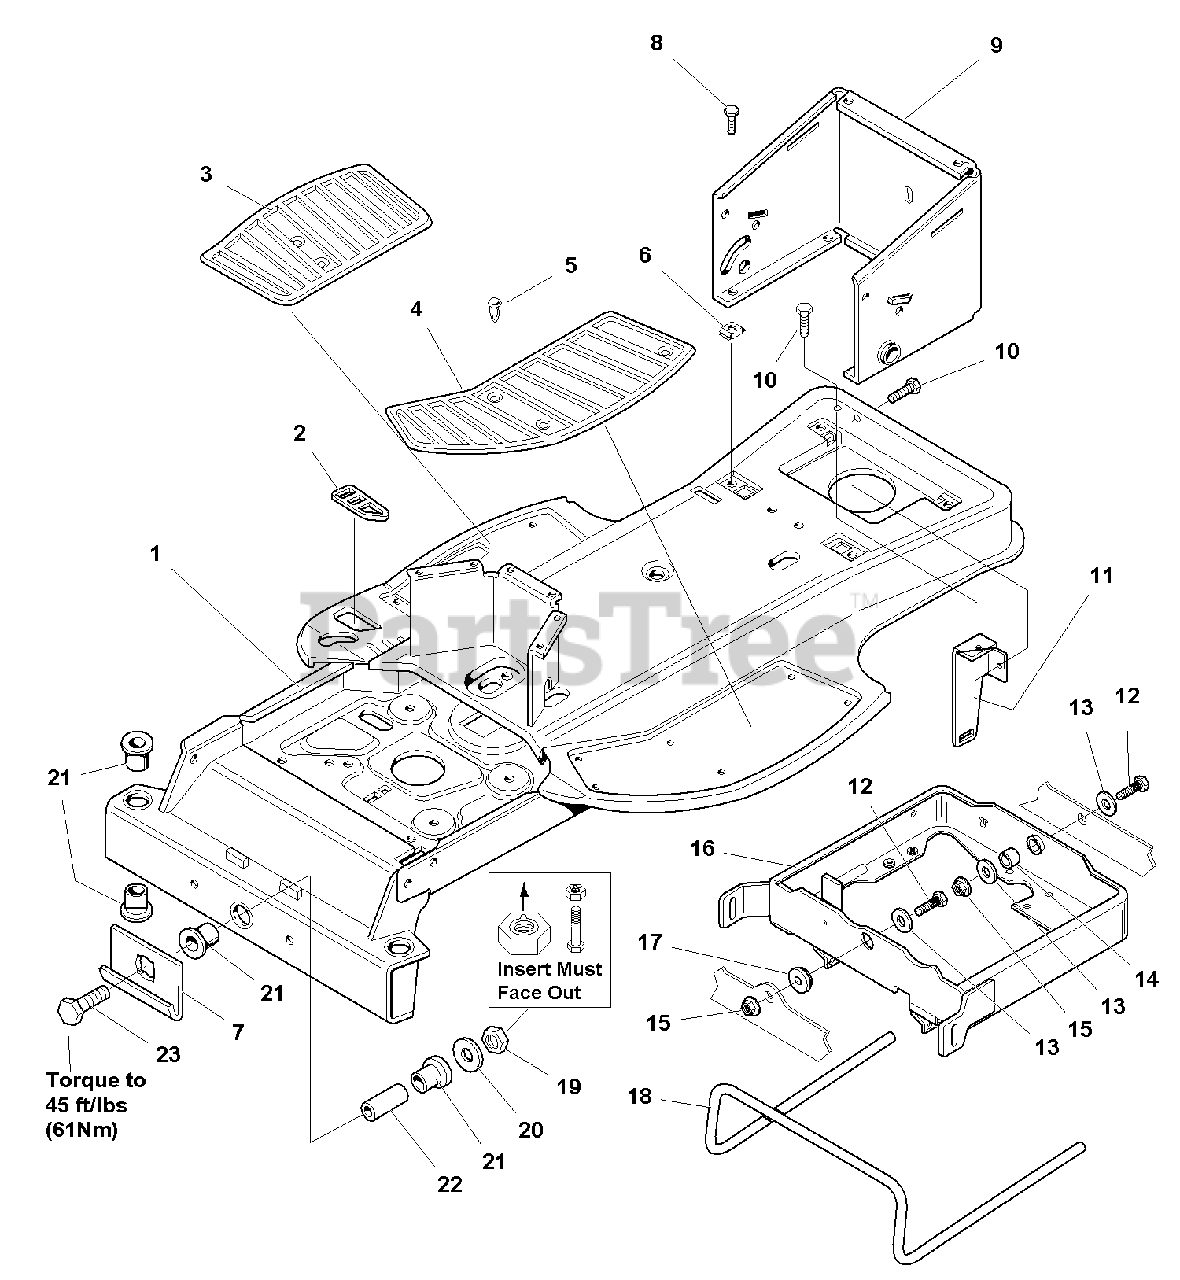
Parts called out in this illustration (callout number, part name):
1	FRAME ASSEMBLY
3	PAD, Footrest RH
4	PAD, Footrest LH
5	FASTENER, Panel
6	NUT, Speed 5/16-18
7	"J" HOOK, Hitch
8	SCREW, Hex Head Flange Lock, 5/16-18 x 3/4
9	WRAPPER ASSEMBLY, Hydro
10	CAPSCREW, Hex Head Flange Whiz Lock, 5/16-18 x 3/4
12	CAPSCREW, Hex Head, 1/2-13 x 1/2
13	WASHER
15	NUT, Hex Head, 1/2-13
16	CARRIER ASSEMBLY, Hydro
18	BAR, Torsion, Hydro
19	NUT, Hex Head Aluminum Insert, 3/8-16
20	WASHER
23	CAPSCREW, Hex Head, 3/8-16 x 3, G8
